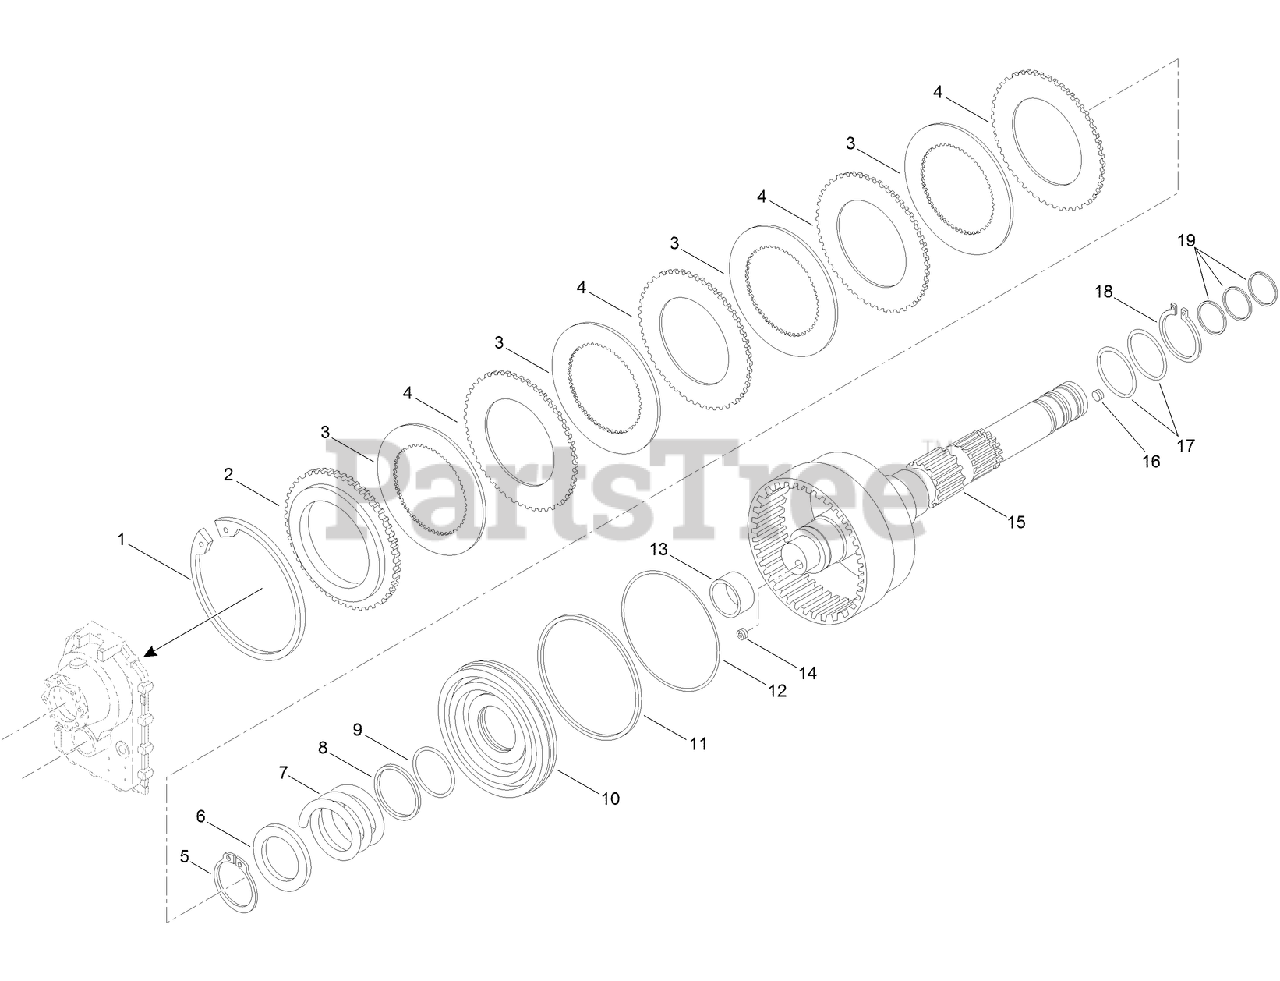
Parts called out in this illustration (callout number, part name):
2	PLATE-BACKING, CLUTCH
3	PLATE-FRICTION
4	PLATE-SEPARATOR
5	RING-RETAINING
6	RETAINER-RETURN SPRING, PISTON
7	SPRING-RETURN, PISTON
10	PISTON-CLUTCH, PTO
11	SEAL-PISTON, EXTERNAL
13	BUSHING
14	PLUG-M10X1
15	CLUTCH SHAFT ASM
17	SEAL-TRANSMISSION
18	RING-RETAINING, EXT
19	RING-SEALING, SHAFT
